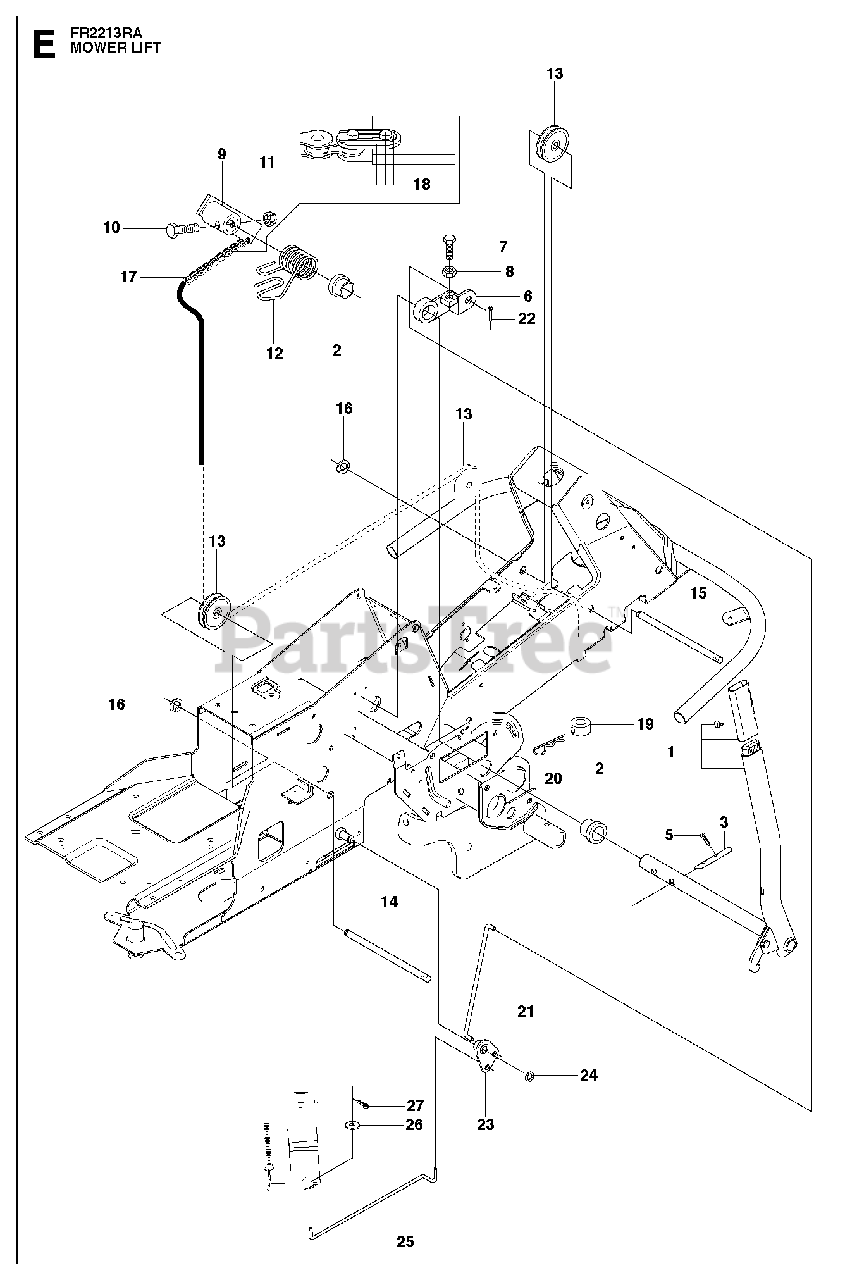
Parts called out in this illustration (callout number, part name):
1	LIFTING LEVER ASSY
2	BUSH
5	SPLIT PIN
6	LEVER CLUTCH
9	LIFTING ARM
16	LOCK RING
21	CONNECTION ROD
22	SPLIT PIN
24	RETAINING RING
25	CONNECTION ROD
27	SPLIT PIN
